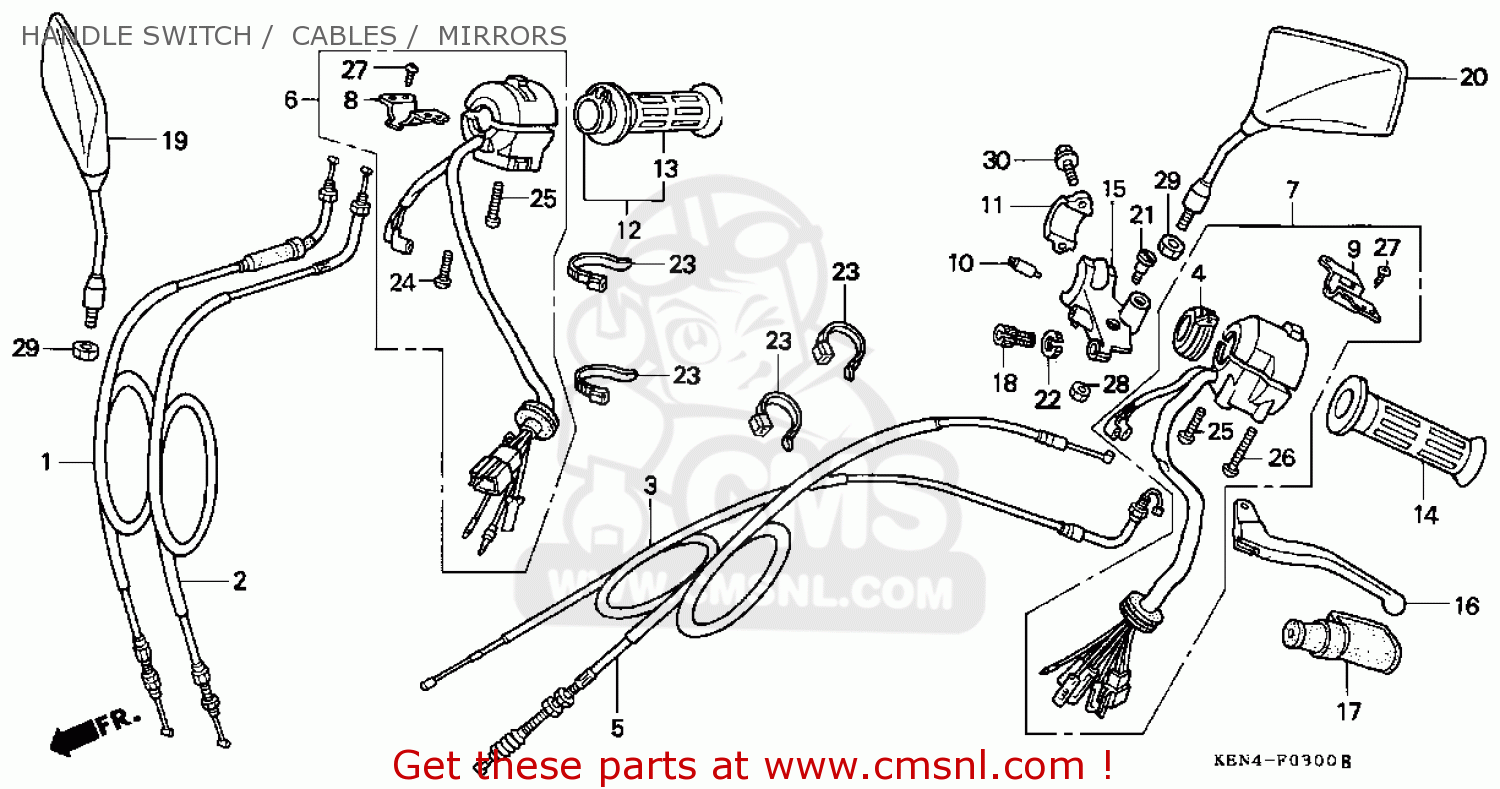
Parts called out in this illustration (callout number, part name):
1	CABLE COMP,A THRO
2	CABLE COMP,THROT.
3	CABLE COMP.CHOKE
4	LEVER,CHOKE
5	CABLE COMP.CLUTCH
6	SET,SW ASSY.ST KI
7	SET,SW ASSY.WINKE
8	PLATE SET
9	PLATE SET
10	SWITCH,FR.LEVER
11	HOLDER,MASSTER CY
12	GRIP COMP.,THROTT
13	GRIP,R.HANDLE
14	GRIP,L.HANDLE
15	BRACKET,HANDLE LE
16	LEVER COMP.,L HND
17	BOOT,HANDLE LEVER
18	BOLT
19	MIRROR COMP,R BAC
20	MIRROR COMP,L BAC
21	BOLT,LEVER PIVOT
22	NUT,FIXING
23	BAND,WIRE
24	SCREW WASHER 5X20
25	SCREW-WASHER,5X28
26	SCREW-WASHER,5X45
27	SCREW,TAPPING,3X8
28	NUT,HEX 6MM
29	NUT,HEX 10MM
30	BOLT,FLANGE,6X22
